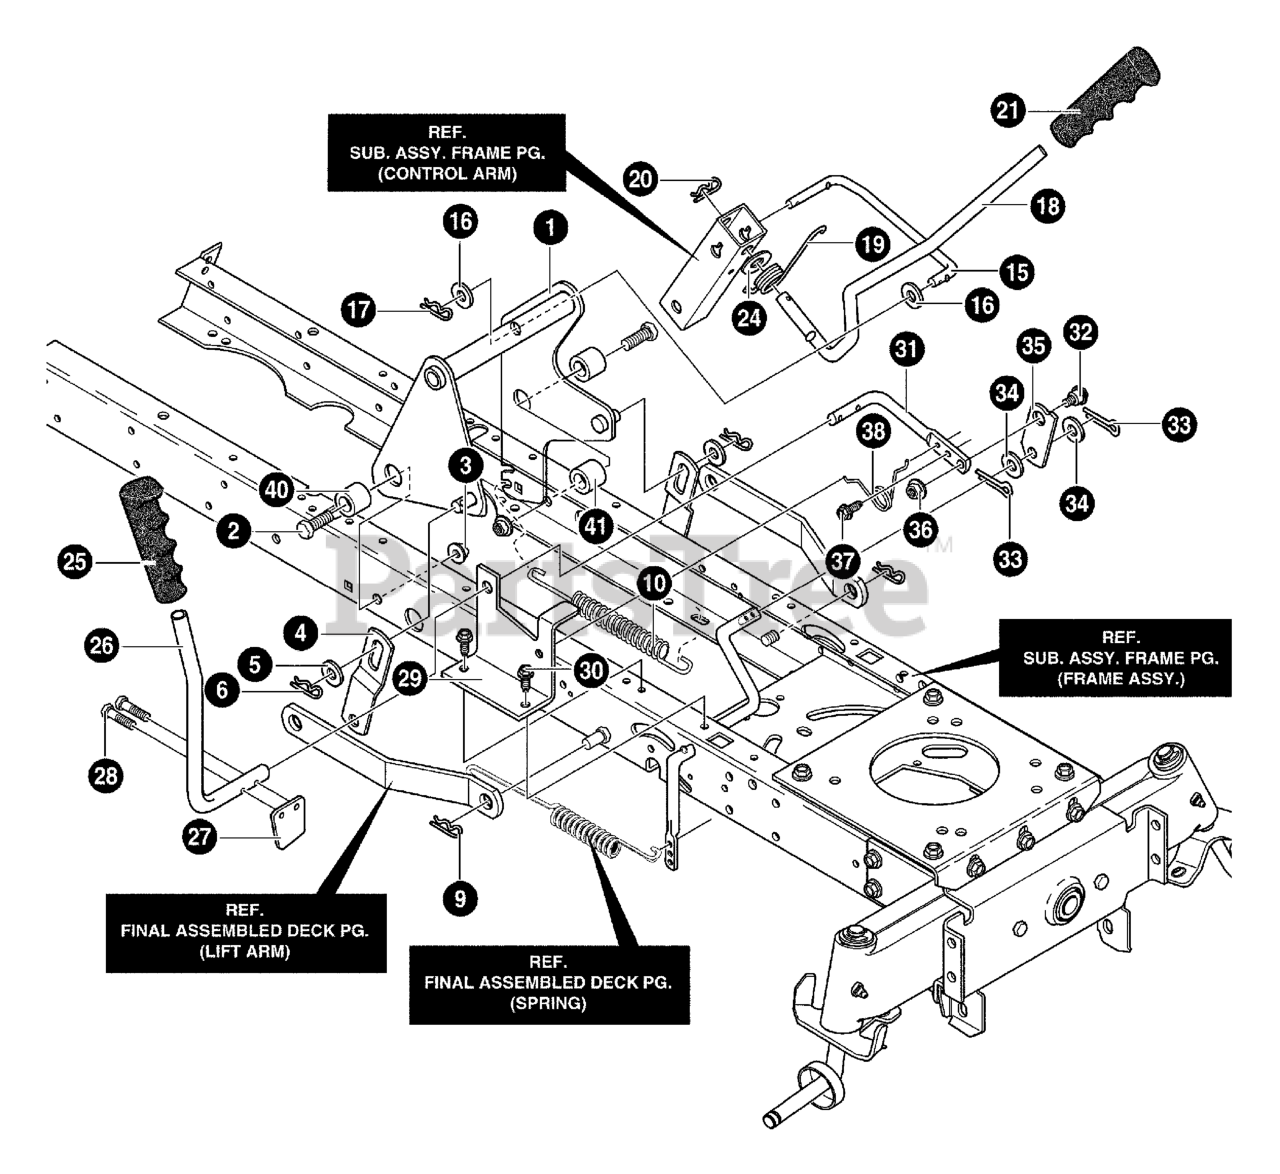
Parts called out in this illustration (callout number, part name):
1	ASM., LIFT ARM
2	SCREW, 1/2-13X1.50
3	NUT, 1/2-13 LOCK
4	BRACKET, LIFT LINK
5	WASHER, FLAT
6	PIN, HAIR
9	PIN, HAIR
10	SPRING, EXTENSION 9.82X1.01OD
15	LINK-LIFT HANDLE
16	WASHER, FLAT
17	PIN, HAIR
18	ZINC HANDLE, LIFT
19	TORSION SPRING .657LG
20	PIN, HAIR
21	GRIP, LIFT
24	WASHER, FLAT .550X1.00X11
25	GRIP, PTO 5/8"
26	PTO HANDLE
27	ZINC PADDLE, SWITCH
28	SCREW, THD FORM .246X1.050LG
29	BRACKET, PTO
30	SCREW, 5/16-18 x 0.50 WAHHTAP
31	ZINC LEVER, PTO
32	BOLT, .50X.75 HHSH 3/8-16
33	PIN, HAIR .072DIAX1.13LH
34	WASHER, FLAT .518X.87X16
35	ZINC LINK PTO
36	NUT, 3/8-16 HWDFLLK MACK
37	SCREW, 5/16-18 x 0.75 HHWATAP
38	TORSION SPRING
40	SPACER .513IDX.880OD
41	SPACER, SLEEVE .94X1.13X.531
